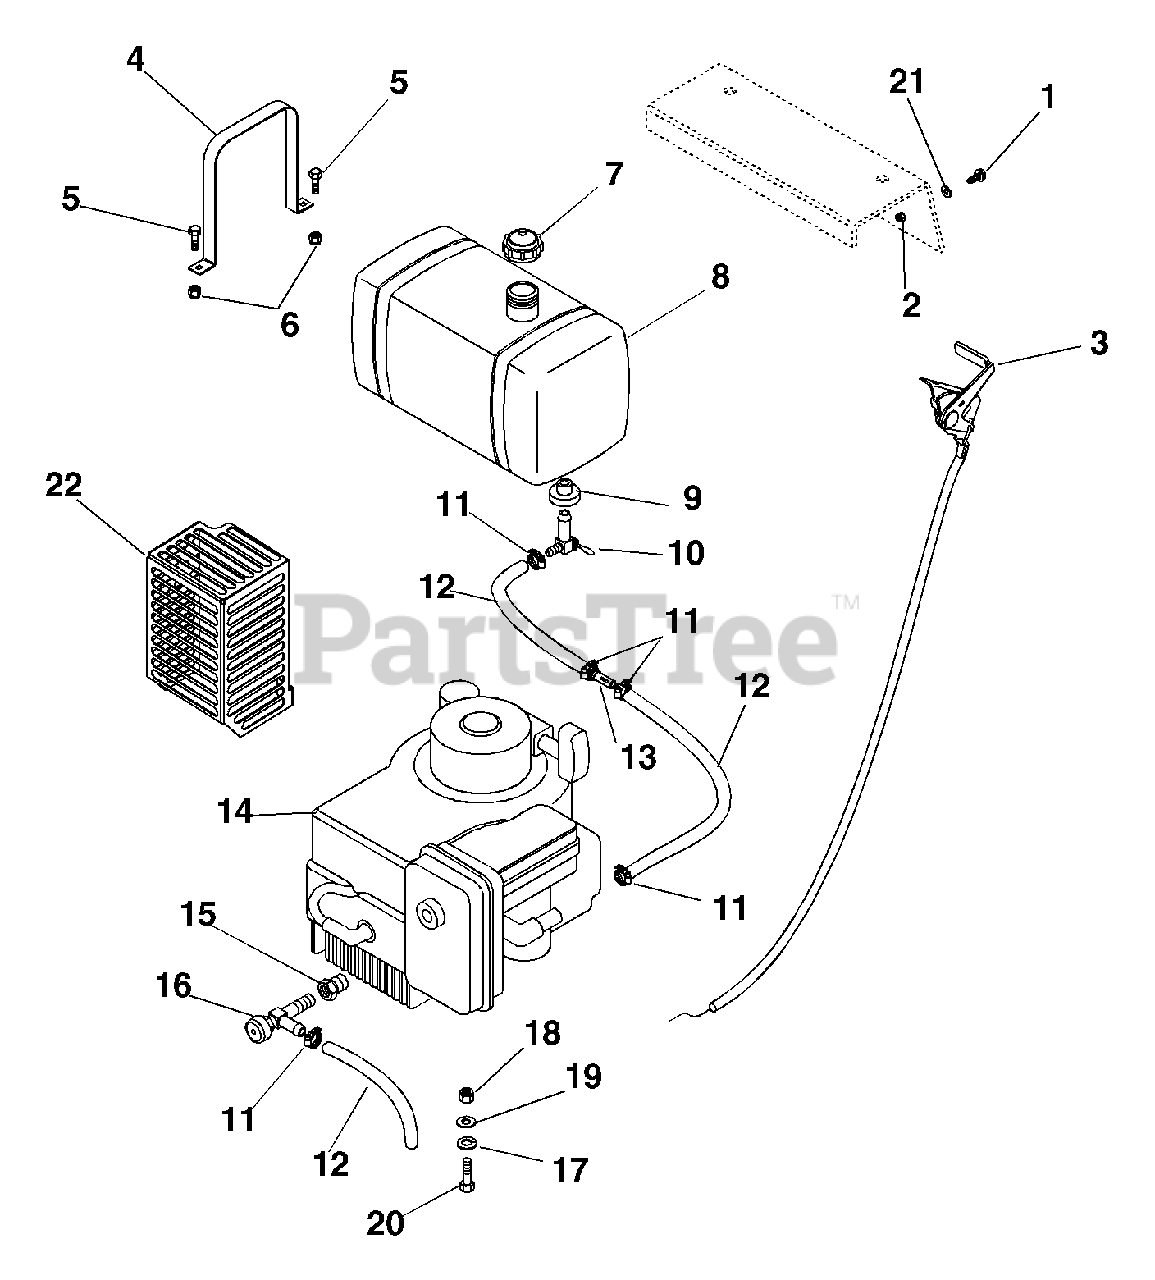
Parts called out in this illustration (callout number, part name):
1	@SCR-MCH 10-24X.50 HWH YWZC
2	@NUT-LK-NYL 10-24 W/INSRT YWZC
3	CABLE, CONTROL
4	TANK STRAP FOR 4.5 G FUEL TANK
5	@BLT-HEX .25-20X.75 GR5 YWZC
6	@NUT-LK-CTR .25-20 YWZC
7	CAP, FUEL TANK
8	FUEL TANK, 4.5 GALLON
9	BSHG-FLG .375 X 1.062 X .625 R
10	VALVE,BALL SHUT-OFF
11	HOSE CLAMP
12	HOSE, .25 LOW-PERM BULK GAS
13	FILTER,FUEL
14	ENG,KAWASAKI SPEC GS01
15	ADPT,OIL DRAIN
16	DRAIN, 1/2" OIL
17	@WSHR-LK .31X.078 REG YWZC
18	@NUT-LK-CTR .31-18 YWZC
19	@WSHR-FL-STL.344X.688X.065YWZC
20	@BLT-HEX M8 X 1.25X30 GR5 YWZC
21	@WSHR-FL-STL.219X.50X.049 YWZC
22	WLDMT, MUFFLER GUARD
